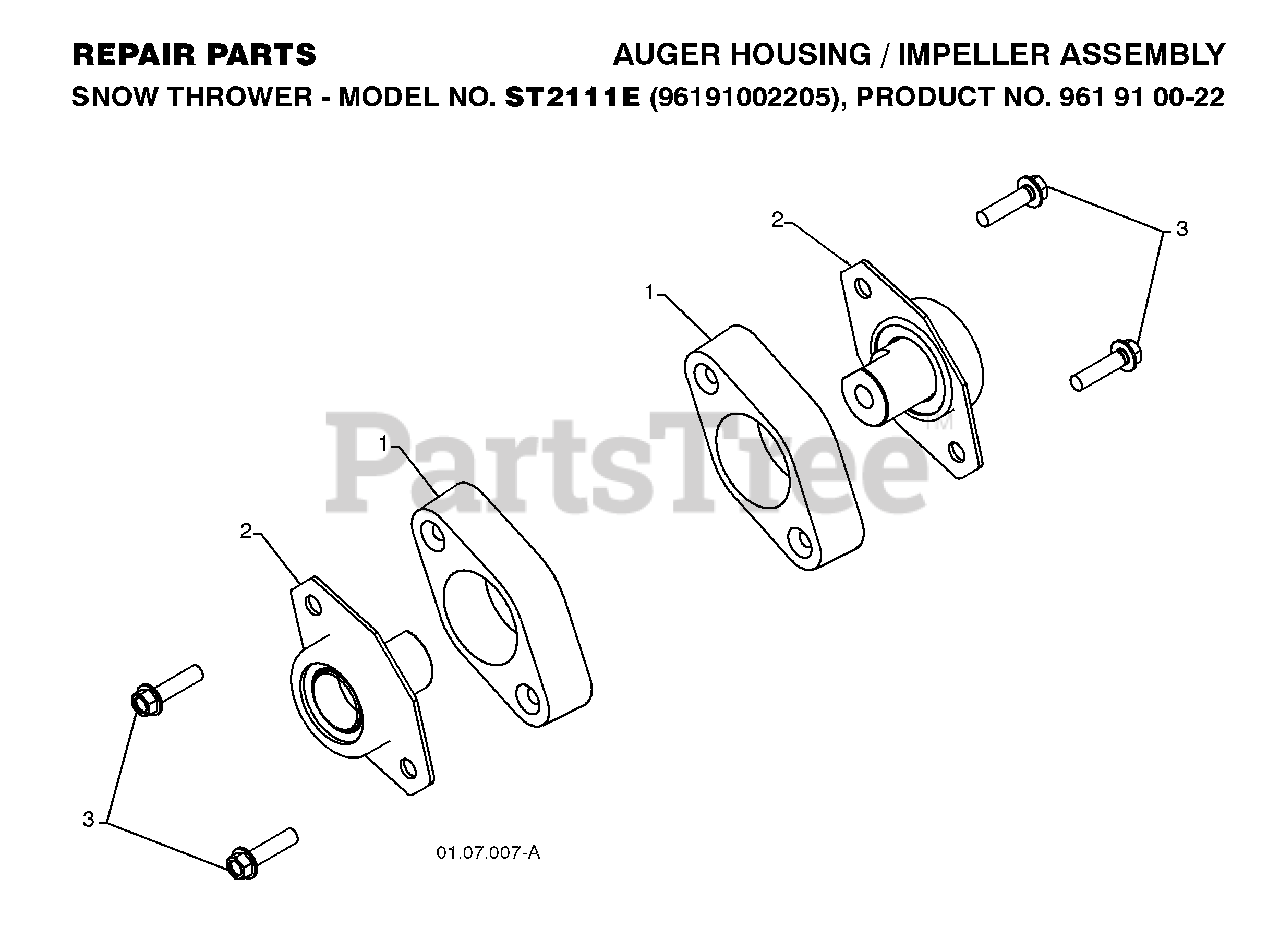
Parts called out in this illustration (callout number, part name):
1	BEARING RETAINER, PLASTIC
2	BEARING.BALL.AUGER
3	SCREW, HEX HD 5/16X1
